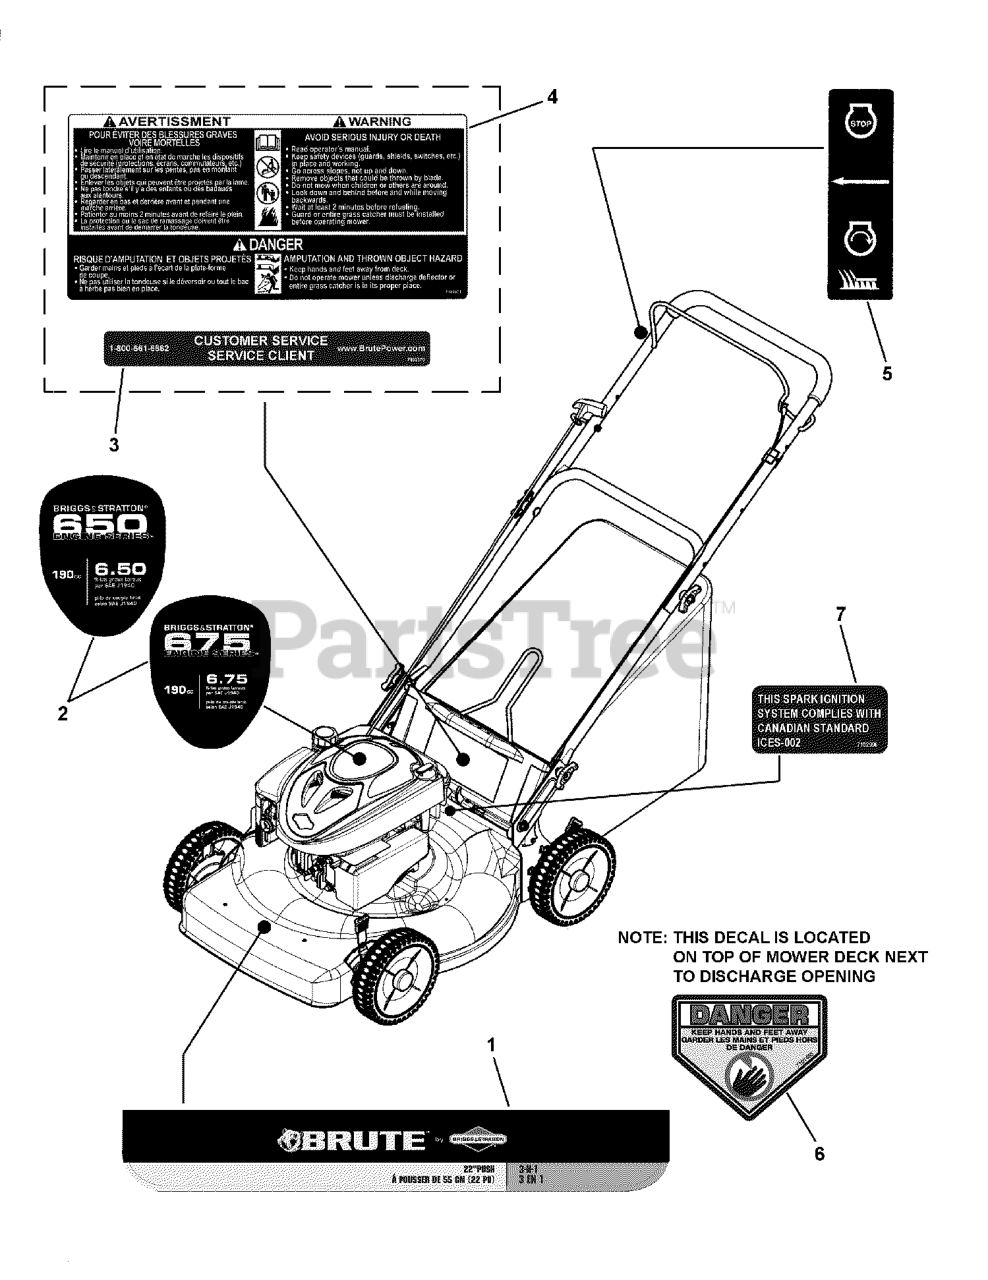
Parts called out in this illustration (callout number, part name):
1	DECAL, Deck Front Brute 22" FC
2	DECAL, Engine, TP, Brute, 675, French Canadian
4	DECAL, French/English, Walk-Behind Safety
5	DECAL, OPC Bail, International Symbol
6	DECAL, CPSC, (Cut Finger) French/English
7	DECAL, ICES, Canadian Spark Compliance
